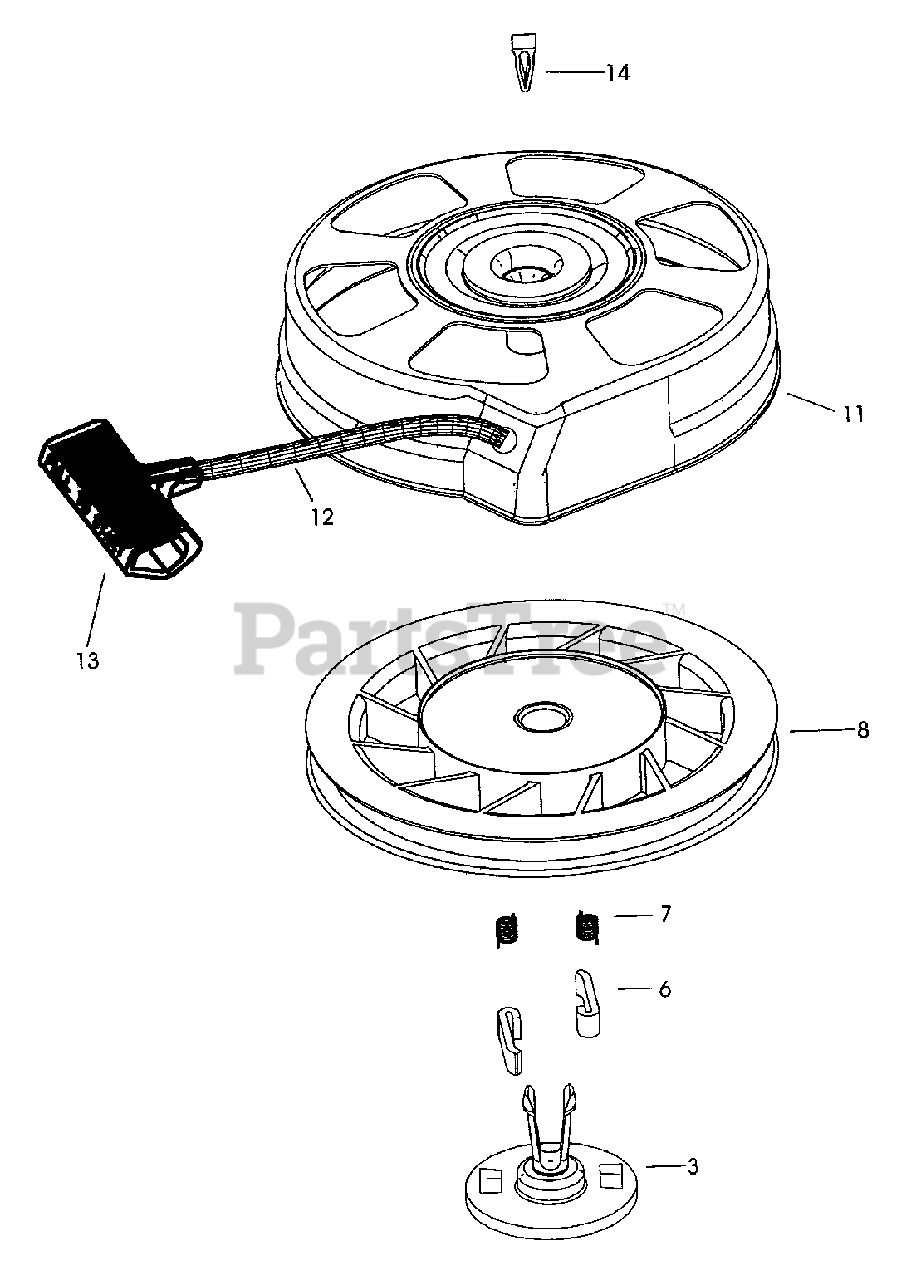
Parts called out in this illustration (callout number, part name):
3	Retainer
6	Starter Dog
7	Dog Spring
8	Pulley & Rewind Spring ASM
11	Starter Housing ASM (40 degree grommet)
12	Starter Rope (Length 98" x 9/64" dia.)
13	Starter Handle
14	Locking Tab
